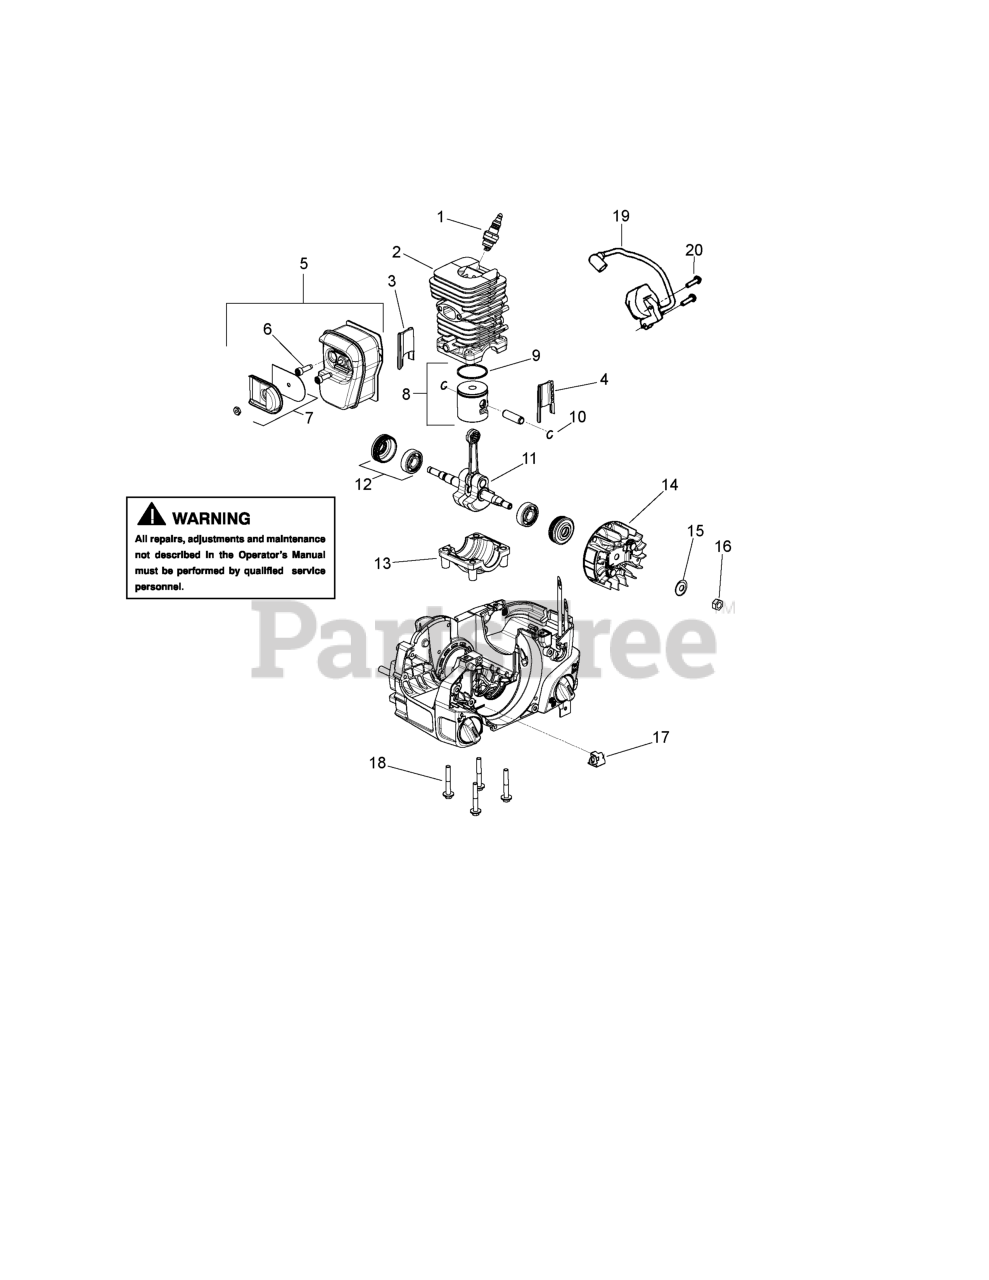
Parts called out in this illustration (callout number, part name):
1	SPARK PLUG
2	Kit-Cylinder
3	Insert-Right (gray) Cyl.
4	Insert-Left (black) Cyl.
5	MUFFLER ASSY
6	Screw - Muffler
7	SPARK ARRESTER
8	KIT SVC PISTON NV PLATED SAS
9	PISTON RING 42CC
10	Retainer - Piston Pin
11	CRANKSHAFT GVG
12	BEARING & SEAL ASSEMBLY
13	CAP CRANKCASE
14	Assy-Flywheel
15	Washer #10 -14 - Flywheel
16	Nut- Flywheel
17	STRAP GROUND SAS2
18	BOLT
19	MODULE SAS2 PHELON
20	SCREW M5.38-14X22.225MM
